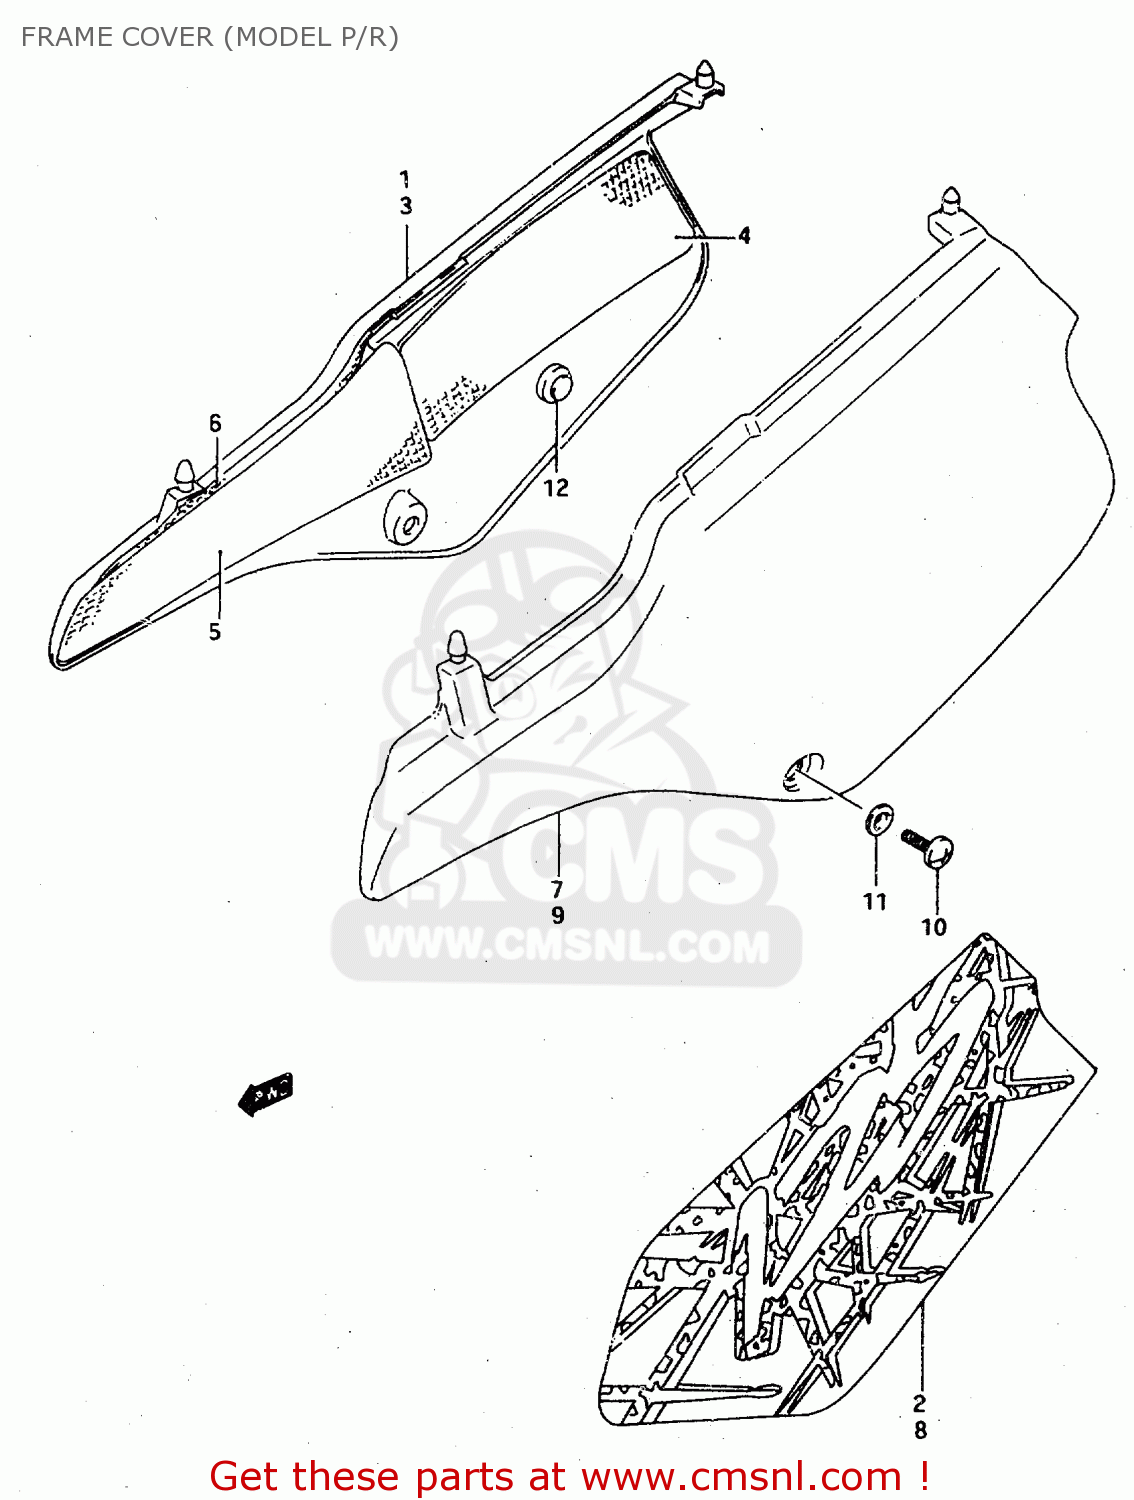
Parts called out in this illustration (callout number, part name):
1	COVER, FRAME RH (WHITE)
2	TAPE, FRAME COVER RH
3	COVER,FRAME,R(WHITE)
4	HEATSHIELD,FRAME COVER,R
5	HEATSHIELD,FRAME COVER,R
6	SHIELD, FRAME COVER RH NO.3
7	COVER, FRAME LH (WHITE)
8	TAPE, FRAME COVER LH
9	COVER,FRAME,L(WHITE)
10	COVER, FRAME LH (YELLOW)
11	TAPE, LH
12	CUSHION
13	TAPE, LH
14	COVER, FRAME LH (BLUE)
15	TAPE, LH
16	SCREW
17	WASHER
18	CUSHION
